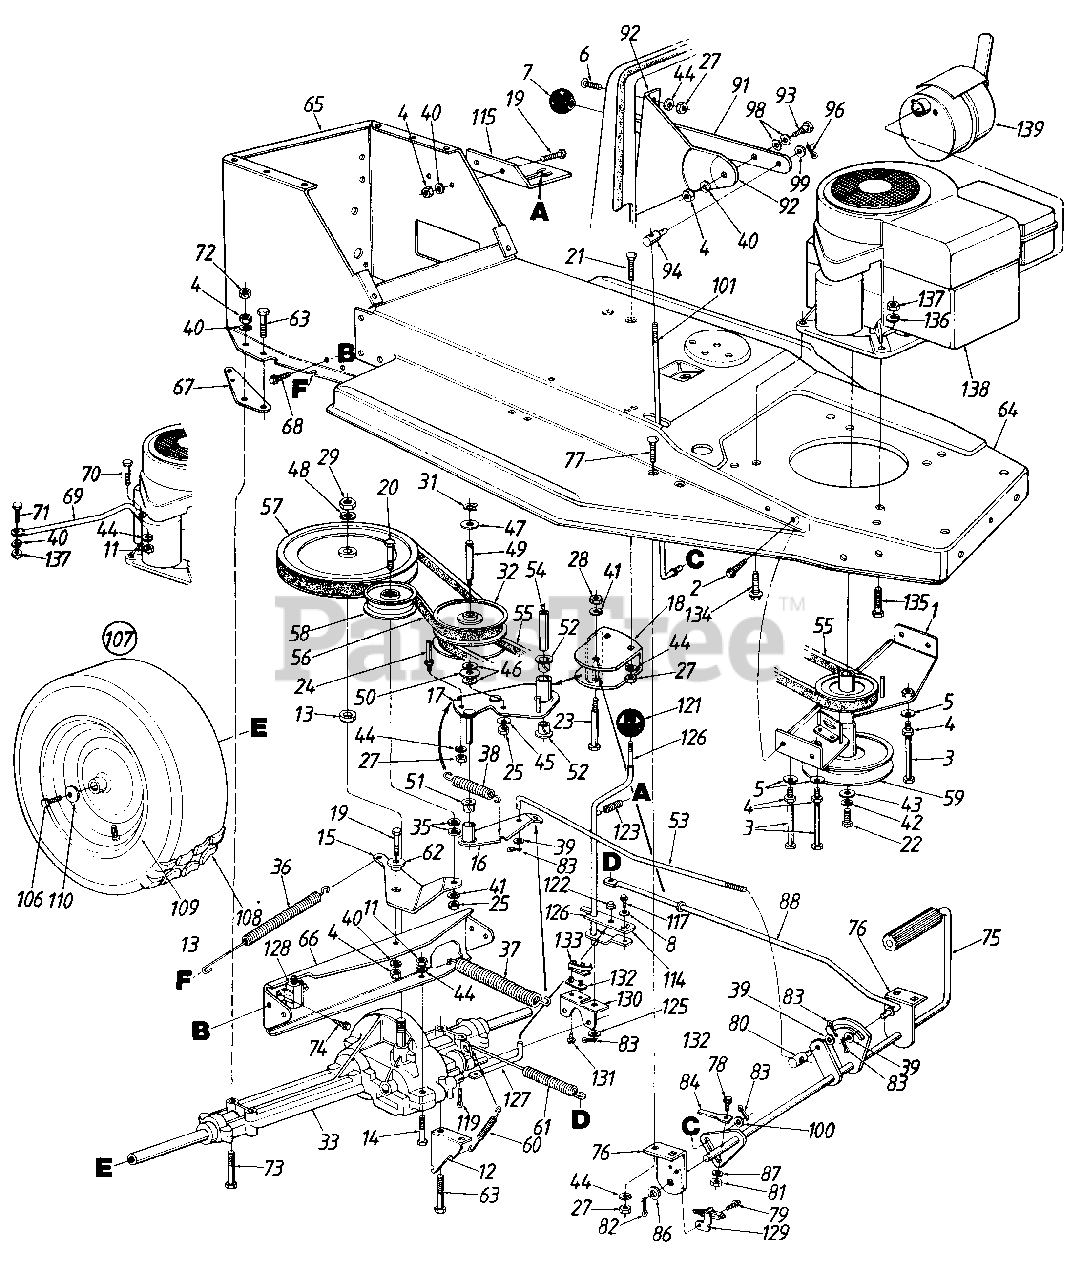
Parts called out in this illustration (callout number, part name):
1	Engine Pulley Belt Guard Ass'y.
2	Hex AB-Tap Scr. 1/4 x .62"
3	Hex Bolt 5/16-18 x 51/4" Lg.
4	Hex Nut 5/16-18 Thd.
5	Bell-Wash. .345" I.D. x .88
6	Truss-Mach. Scr. 1/4-20 x .50" Lg.
7	Gear Shift Knob
8	Bell-Wash. .265" I.D. x .75
11	Hex Nut 1/4-28 Thd.
12	Spring Retainer Brkt.
13	Spacer .5" I.D. x .93"
14	Hex Bolt 1/4-28 x 1.75" Lg.
15	Idler Bracket
16	Variable Speed Torque Brkt. Ass'y.
17	Variable Speed Brkt. Ass'y.
18	Variable Speed Pivot Brkt.
19	Hex Bolt 5/16-18 x .75" Lg.
20	Hex Bolt 3/8-24 x 13/4" Lg. Gr. 5
21	Carr. Bolt 1/4-20 x .75" Lg.
22	Hex Bolt 7/16-20 x 1.5" Lg.
23	Hex Bolt 3/8-16 x 2.5" Lg.
24	Belt Guard Pin
25	Hex Nut 3/8-24 Thd.
27	Hex Nut 1/4-20 Thd.
28	Hex Nut 3/8-16 Thd.
29	Hex Jam Nut 1/2-20 Thd.
31	Snap Ring
32	Variable Speed Pulley Ass'y.
33	Transaxle Complete
35	Fl-Wash. 3/8" I.D. x 1"
36	Extension Spring 6.12" Lg.
37	Extension Spring 7.5" Lg.
38	Extension Spring 2.59" Lg.
39	Fl-Wash. .385" I.D. x .620"
40	L-Wash. 5/16" I.D.*
41	L-Wash. 3/8" I.D.
42	L-Wash. 7/16" I.D.
43	Fl-Wash. .450" I.D. x 1.25"
44	L-Wash. 1/4" I.D.
45	Bell-Wash. .39" I.D. x 1.13"
46	Fl-Wash. .56" I.D. x 1.0" O.D.
47	Washer "Teflon" .565 I.D.
48	L-Wash. 1/2" I.D.
49	Shaft .56" Dia. x 3.875" Lg.
50	Thrust Brg. 1.25 O.D.
51	Flanged Nyliner Brg.
52	Nyliner Flanged Brg.
53	Speed Control Link
54	Spacer
55	V-Belt
56	V-Belt
57	1/2 V-Pulley .500" I.D. x 8.00"
58	Idler Pulley 3-1/8" Dia.
59	Dbl. Pulley 6.0" Dia. x 3.56"
60	Extension Spring 3.18" Lg.
61	Extension Spring 7.08" Lg.
62	Shld. Spacer .500" Dia.
63	Hex Bolt 5/16-18 x 2.75" Lg.*
64	Front Frame
65	Rear Frame
66	Transaxle Support Brkt.
69	Support Brace
70	Hex Bolt 1/4-28 x .75"
71	Hex Bolt 5/16-24 x .75"
72	Hex L-Nut 5/16-18 Thd.
73	Hex Bolt 5/16-18 x 3.0" Lg.*
74	Truss Mach. B-Tap Scr. #10 x.50" Lg.
75	Clutch/Brake Pedal Ass'y.
76	Clutch/Brake Pedal Mounting Brkt.
77	Carr. Bolt 1/4-20 x .62" Lg.
78	Hex Bolt 1/4-20 x 1.0" Lg.*
79	Hex TT-Tap Scr. 1/4-20 x .5" Lg.
80	Ferrule
82	Cot-Pin 3/32" Dia. x 1.0" Lg.
83	Cot-Pin 3/32" Dia. x .75" Lg.
84	Switch Actuator
86	Fl-Wash. .635" I.D. x 1.0n
88	Brake Rod
91	Speed Selector Lever
92	5 Speed Selector Brkt.
93	Shld. Bolt .437" x .35"
94	Ferrule
96	Intern. Cot-Pin 5/16" Dia.
99	Fl-Wash. .344" I.D. x .62"
100	Fl-Wash. .25" I.D. x .62n O.D.
101	Speed Control Rod
106	Hex L-Bolt 5/16-24 x .75" Lg.
107	Rear Wheel Ass'y. Comp.
110	Bell-Wash. .345" I.D. x .88"
114	Shift Lever Adjusting Link
115	Shin Lever Spring Brkt.
117	Hex Bolt 1/4-20 x .50 Lg.*
119	Intern. Cotter Pin
121	Ball Knob
122	Retaining Ring
123	Compression Spring 1.5 Lg.
125	Fl-Wash. .469" I.D. x .88"
126	Bhin Rod Ass'y.
127	Shift Rod
128	Safety Switch
129	Safety Switch
130	Shift Lever Support
131	Hex Wash. Hd. AB-Tap Scr. #8 x .5" Lg.
132	Insulator Nut Plate
133	Spring Switch
134	Hex Wash. Hd. Tap Scr. 3/8-16 x 1.25" Lg.
135	Hex Bolt 5/16-24 x 11/4" Lg. Grade 5
136	L-Wash. 5/16" I.D.
137	Hex Nut 5/16-24 Thd.
138	Engine
139	Muffler Check PN
